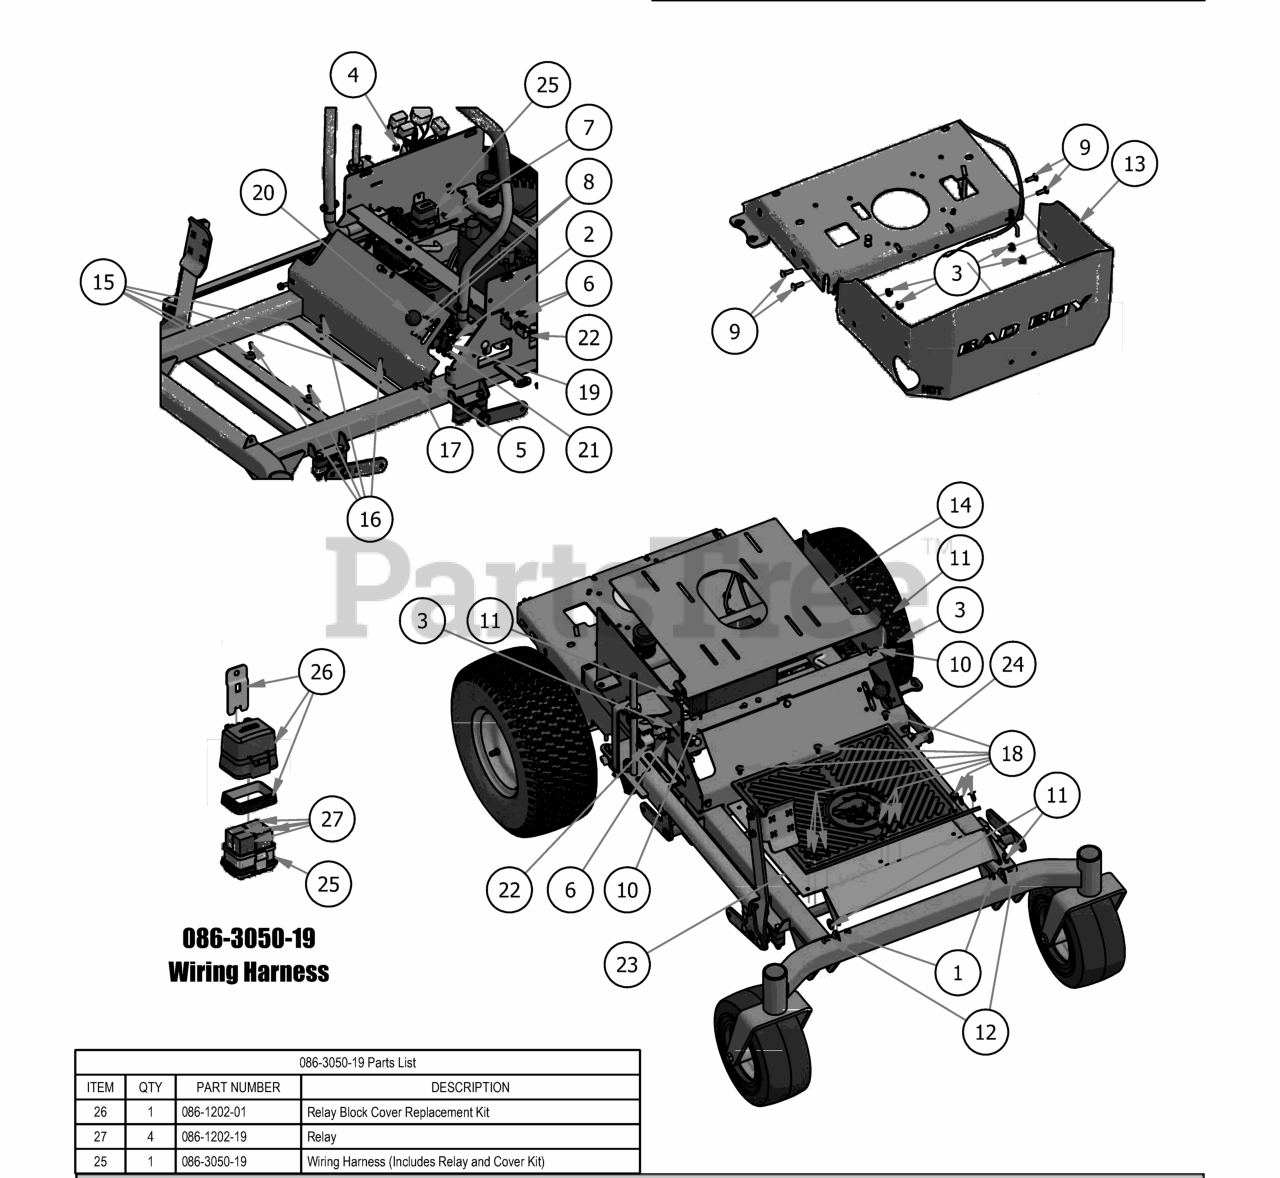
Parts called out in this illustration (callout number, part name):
1	1/4-20 Nylon Insert flange Nut
2	10-24 Nylon Insert Locknut Zinc Orange Nylon
3	5/16" Nylon Flange Nut
4	1/4-20 Hex Flange Nuts Zinc w/Serrations
5	2017 MZ Cooler Cover
6	12-24x 1/2 HWH Bolt
7	1/4" x 1/2" BS C/S 18-8 SS
8	10-24 X 5/8 BS Button Head Bolt
9	5/16" x 1" Carriage Bolt
10	5/16" x 7/8" Carriage Bolt
11	.360ID Plastic Washer
12	1/4" x 3/4" Carriage Bolt
13	2017 MZ Rear Plate
14	2017 MZ Seat Plate
15	Button Bumper
16	#10 x 1/2" Self Tapping Screw
17	5/16 x 3/4 washer head type F screw
18	Ratchet Fastener
19	Universal Throttle
20	Throttle Knob
21	MZ Brake Cable
22	Safety Switch
23	MZ/ZT 2017 Floorboard
24	2017 MZ/ZT Floor Mat
25	Wiring Harness
26	Relay Block Cover Replacement Kit
